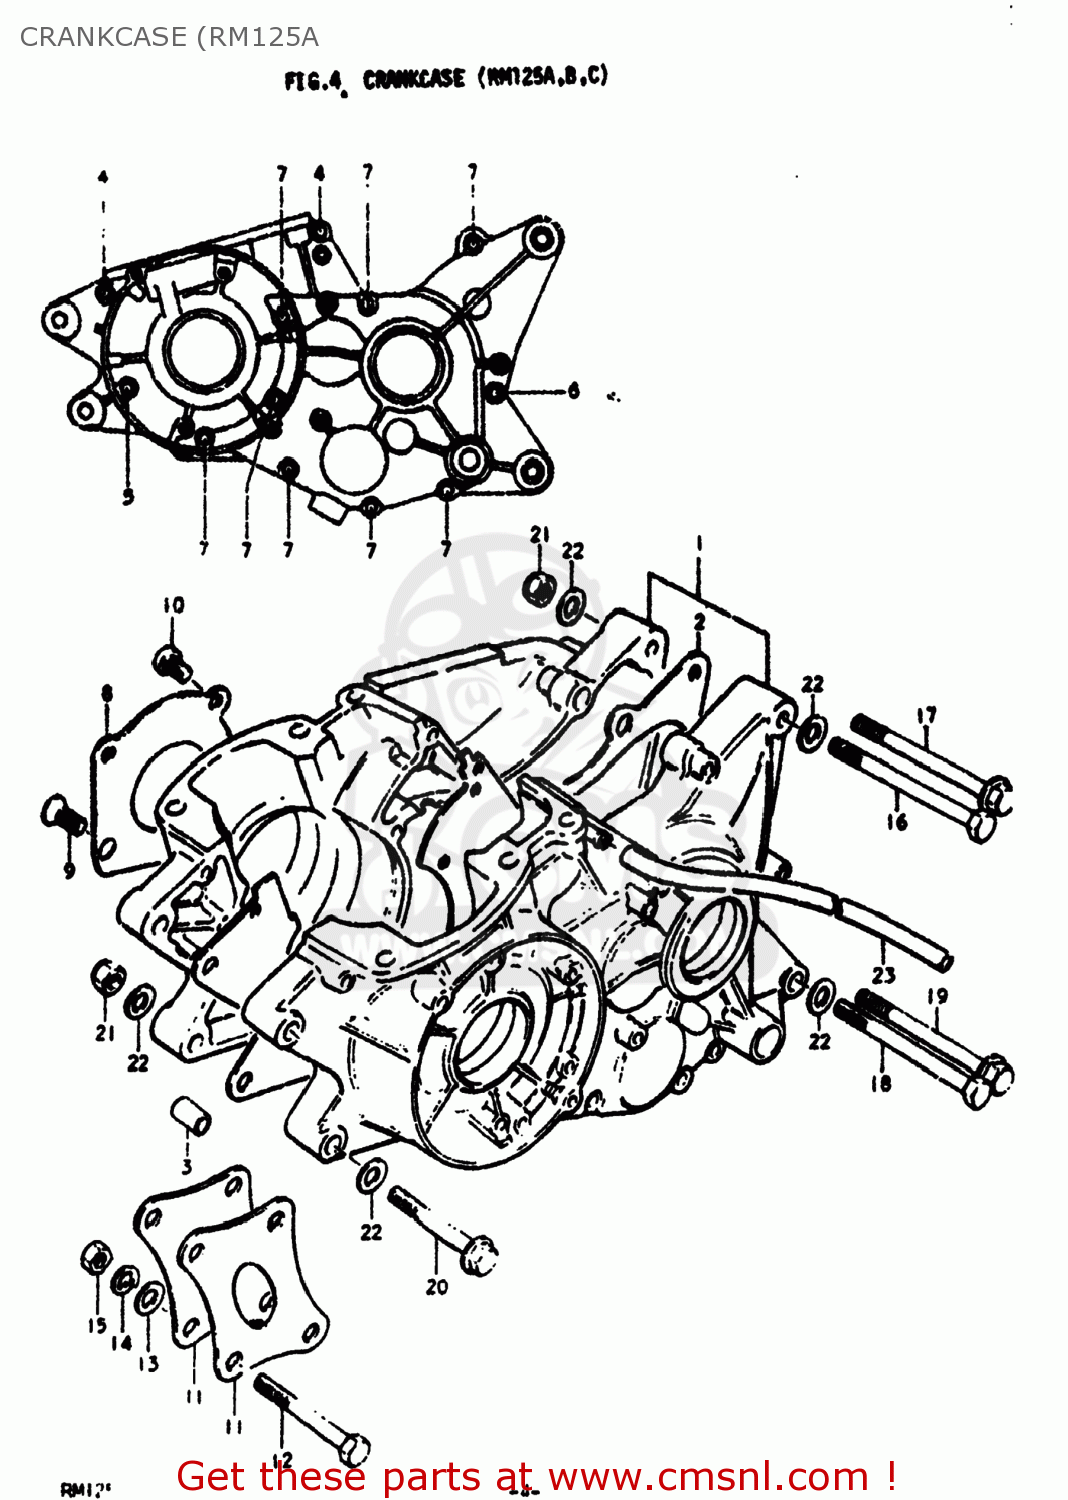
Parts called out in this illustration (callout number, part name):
1	CRANKCASE SET
2	GASKET,CRANKCASE (MCA)
3	PIN
4	SCREW (6X35)
5	SCREW (6X45)
6	SCREW
7	SCREW 6X60
8	PLATE,OIL RESERVOIR
9	SCREW
10	SCREW 6X12
11	PLATE,ENGINE MOUNTING
12	BOLT
13	WASHER
14	LOCK WASHER
15	NUT
16	BOLT 8X105
17	BOLT
18	BOLT 8X100
19	BOLT
20	BOLT (8X70)
21	NUT
22	WASHER
23	HOSE
